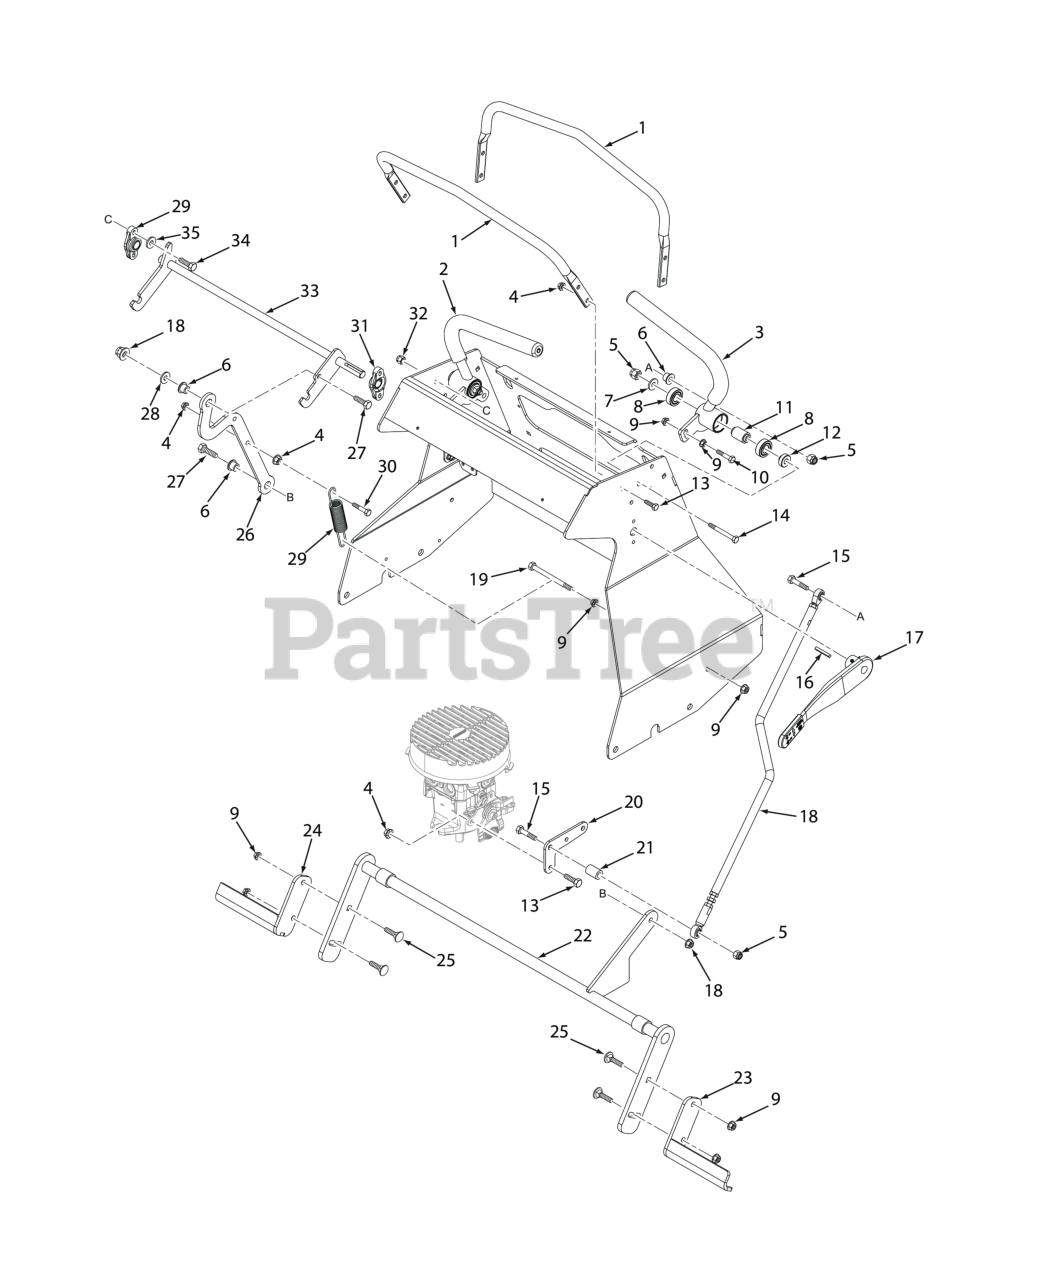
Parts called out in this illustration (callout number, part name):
1	Reference Bar
2	RH Handle Bar Assy.
3	LH Handle Bar Assy.
4	Nut, Serrated Flange 5/16-18 (Right Front Engine Mounting, Briggs and Kohler Only)
5	HEX NUT, ELASTIC STOP LOCK, 3/8-16
6	BUSHING, BRONZE - .376 ID X .627 OD
7	Flatwasher, 3/8 (.391 x .938 x .105 HD) Grade 8
8	BEARINGS, BALL, NEUTRAL RETURN
9	NUT, 3/8-16 SERRATED FLANGE HEX HEAD
10	Capscrew, Hex Head 3/8-16 x 2.0"
11	Spacer, Bearing
12	Spacer, Controls
13	BOLT, SERRATED FLANGE HEX HEAD 5/16-18 X 3/4"
14	Capscrew, Hex Head 3/8-16 x 3.25"
15	Bolt, Hex Head 3/8-16 x 1-1/2" B&S 32BV
16	KEY, 3/16 X 3/16 X 1-1/2
17	Lever Assembly, Brake, SVRII
18	Link, Steering Control
19	Bolt, 3/8-16 x 5.00" Hex Head
20	Pump Linkage Brkt
21	Yoke, Front Caster Wheel
22	Bellcrank Weldment, Brake
23	Brake Paddle Weldment, LH
24	Brake Paddle Weldment, RH
25	Carriage Bolt, 3/8-16 x 1.0"
26	Link, Brake Engage
27	Bolt, Hex Head 3/8-16 x 1-1/4", Kawasaki FX / FT & FT-EFI
28	Flatwasher, 3/8" Special (.391 x .938 x .105)
29	Spring, Deck Lift
30	Bolt, Hex Head 5/16-18 x 1-1/2" (Right Front Engine Mounting, Briggs and Kohler Only)
31	Bearing
32	Nut, Flanged Elastic Stop 1/4-20
33	Lock Weldment, Neutral
34	Capscrew, Hex Head 1/4-20 x 1"
35	Flatwasher, 1/4 (.281 x .625 x .065)
